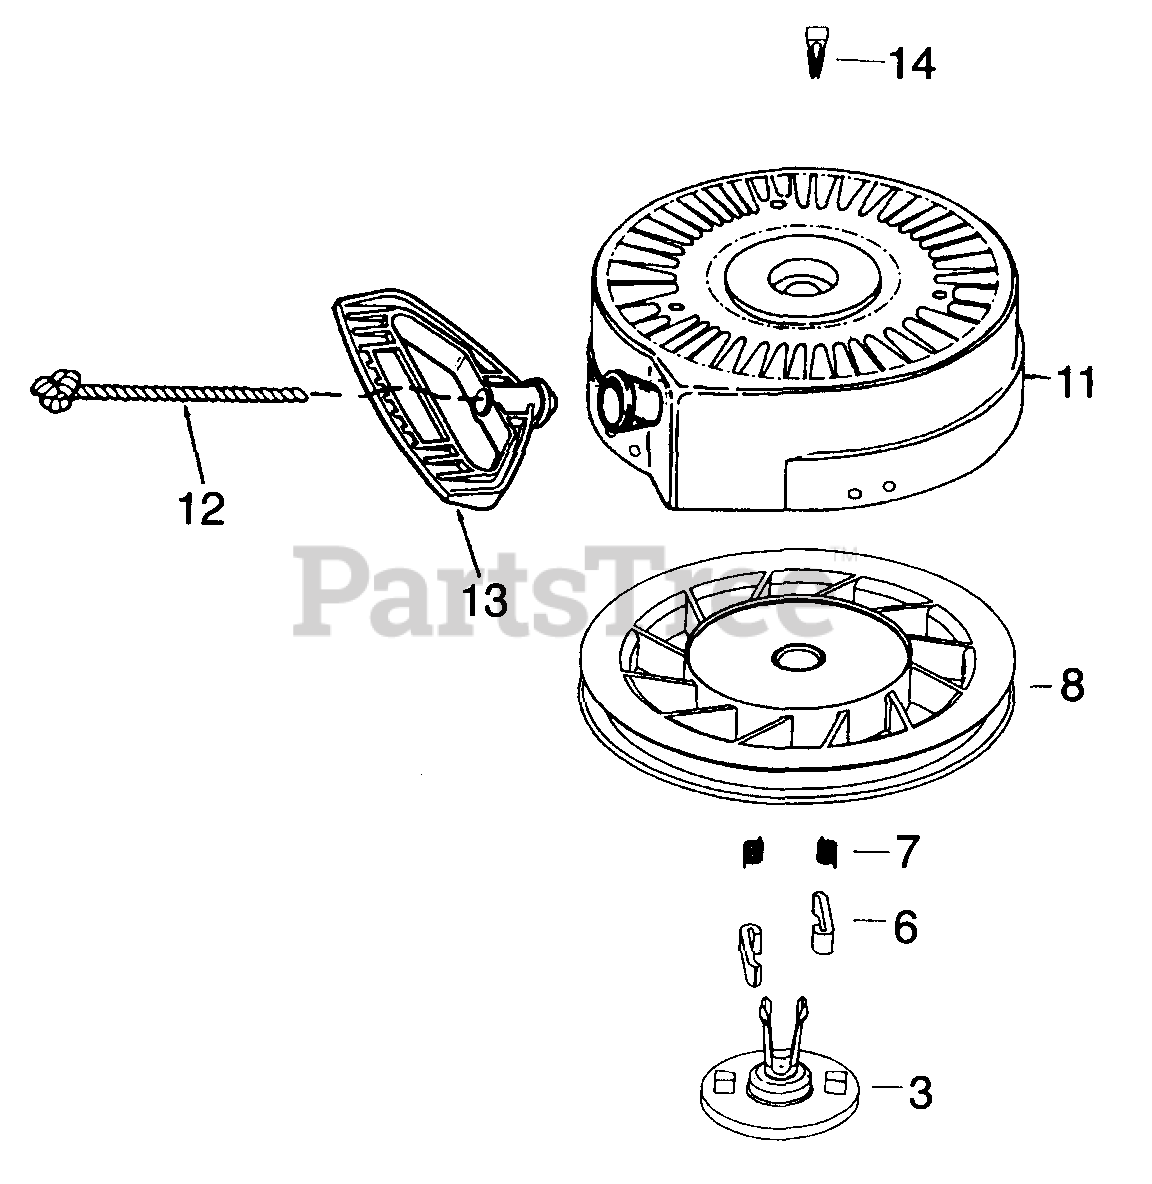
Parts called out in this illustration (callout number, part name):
6	Starter Dog
7	Dog Spring
8	Pulley & Rewind Spring Assy
11	Starter Housing Assy
12	Starter Rope
13	Mitten Grip Handle
14	Locking Tab
